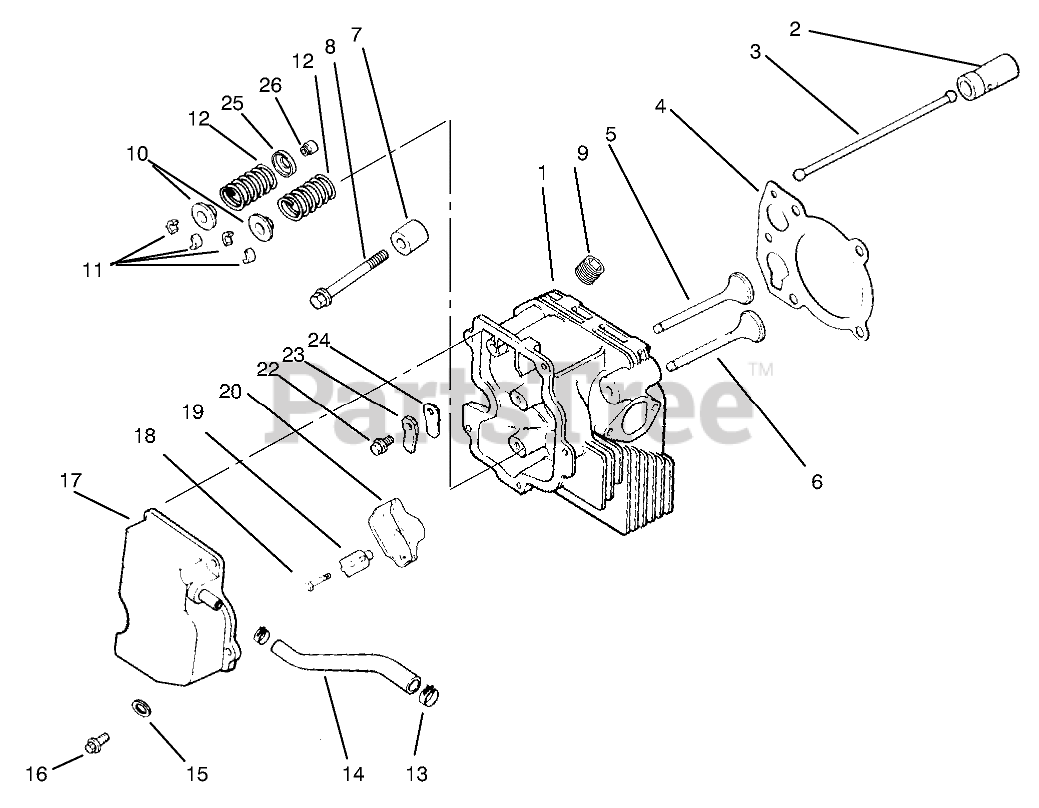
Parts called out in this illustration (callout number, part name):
1	Cylinder Head (Only On: 92003, 92043) On: 92003, 92043)
2	Lifter-Valve (Only On: 92003, 92043)
3	Rod-Push (Only On: 92003, 92043)
4	Gasket-Cylinder Head (Only On: 92003,
4	Gasket-Cylinder Head (Only On: 92043,
5	Valve-Intake STD (Only On: 92003, 92043)
5	Valve-Intake .25 (Only On: 92003, 92043)
6	Valve-Exhaust STD (Only On: 92003, 92043)
6	Valve-Exhaust .25 (Only On: 92003, 92043)
8	Spacer-Head Bolt Exhaust (Only On: 92003, 92043)
9	Screw M10x1.5x80 (Only On: 92003, 92043)
9	Plug (Only On: 92003, 92043)
10	Cap-Valve Spring (Only On: 92003, 92043)
11	Kit-Retainer (Only On: 92003, 92043)
12	Spring-Valve (Only On: 92003, 92043)
13	Clamp-Hose (Only On: 92003, 92043)
14	Hose-Breather (Only On: 92003, 92043)
15	Washer-Flat (Only On: 92003, 92043)
16	Screw-HH M6x1.0x20 (Only On: 92003, 92043)
17	Cover-Valve w/Nipple (Only On: 92003, 92043)
18	Screw M6x1.0x34 (Only On: 92003, 92043)
19	Pivot-Rocket Arm (Only On: 92003, 92043)
20	Arm-Rocker (Only On: 92003, 92043)
22	Screw M5x0.8x10 (Only On: 92003, 92043)
23	Retainer-Breather Reed (Only On: 92003, 92043)
24	Reed-Breather (Only On: 92003, 92043)
25	Retainer-Spring (Only On: 92003, 92043)
26	Seal-Valve Stem (Only On: 92003, 92043)
